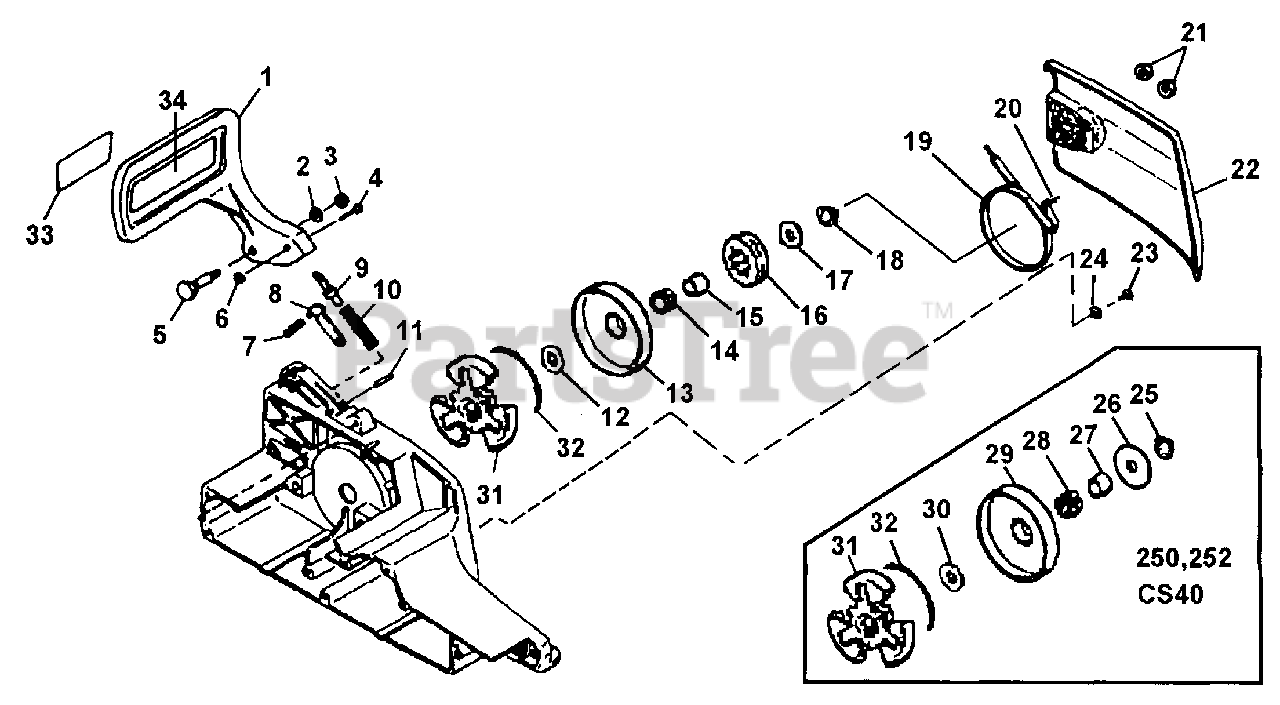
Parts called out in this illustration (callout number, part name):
1	GUARD, HAND
2	WASHER, BELLVILLE
4	PIN
5	SCREW, SHOULDER
6	RING, RETAINER
7	SPRING, COIL
8	BRAKE LATCH ASSY
9	ADJUSTER, BRAKE
10	SPRING, COMPRESSION
11	PIN
12	WASHER, THRUST (INNER)
13	SPLINE & DRUM
14	BEARING, NEEDLE
15	RACE, INNER
17	WASHER, THRUST
18	NUT, HEX LOCK (3/8"-24)
19	BRAKE BAND ASSY
20	PIN, DOWEL
21	NUT, HEX
22	COVER, DRIVE CASE
24	RETAINER, BRAKE BAND
25	NUT, HEX LOCK (3.8"-24)
26	WASHER, THRUST
27	RACE, INNER
28	BEARING, NEEDLE
29	SPROCKET & DRUM
30	WASHER, THRUST
31	CLUTCH ASSY
32	SPRING, CLUTCH
33	LABEL, KICKBACK
34	DECAL, SAFETY
